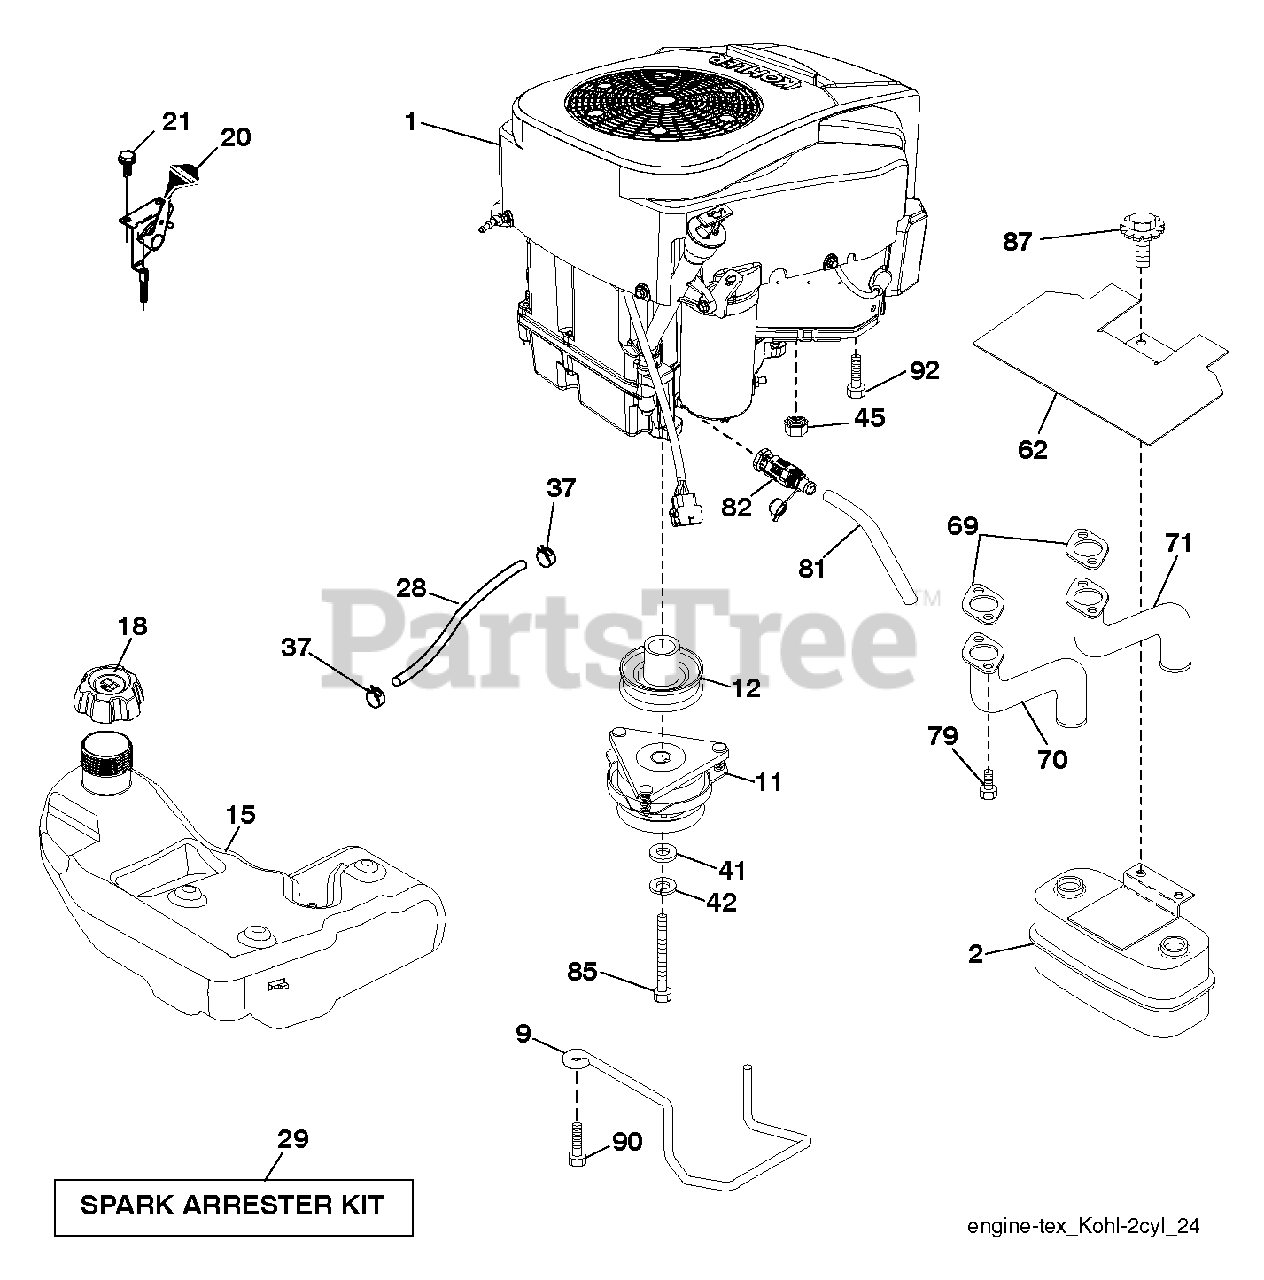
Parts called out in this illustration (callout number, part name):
2	MUFFLER.ASM.TWN.EXTNDED.DFLCTR
9	KEEPER BELT ENGINE
11	Clutch, Ogura 5.0Pd Gt1.5A-Eh01
12	PULLEY ENGINE
15	TANK.ASM.4.GAL.EPA.ONE.PORT
18	Fuel Cap Assembly, 3" Black
20	THROTTLE CONTROL
21	SCREW.#10 X 0.750.BOS (2 2)
28	LINE.FUEL.64"REAR.EMIS
29	KIT.SPARK ARRESTOR(392390 B&S)
37	HOSE CLAMP
42	LOCKWASHER
45	NUT
62	SHIELD.HEAT.MUFFLER
69	GASKET.EXHAUST.KOHL.CV18-CV26
70	Exhaust Pipe, LH CV18/20
71	Exhaust Pipe, RH CV18/20
79	SCREW.SOCKET HD.5/16-1
81	TUBE, DRAIN OIL ASM.
82	VALUE.OIL.DRAIN
85	Hex Bolt, 7/16-20 X 3.0 Gr5
87	BOLT.5/16-18UNCX1.W/SEMS.BLK
90	SCREW 3/8-16X1
92	SCREW 3/8-16X1
